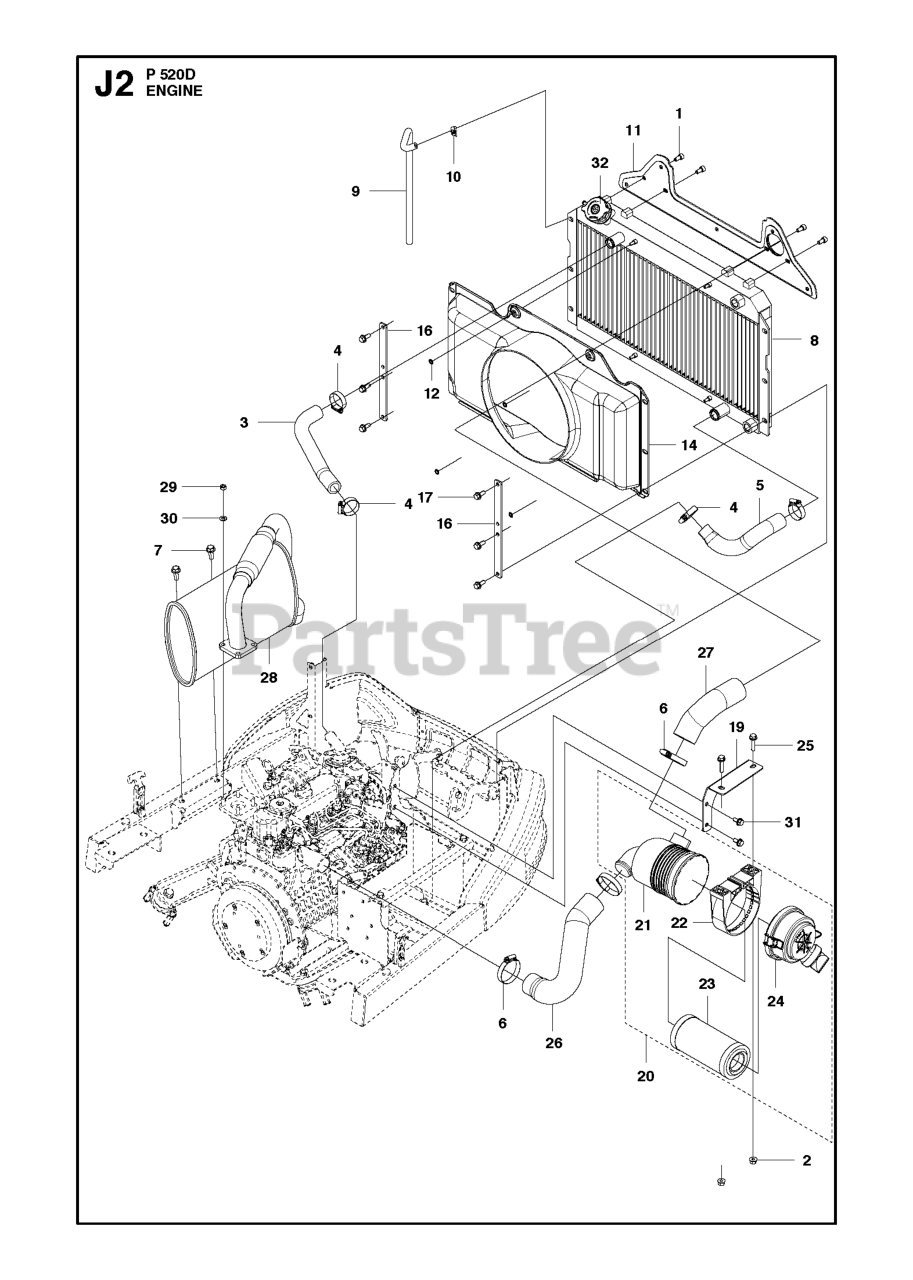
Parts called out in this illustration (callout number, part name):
2	NUT FLANGE
10	HOSE CLAMP FUEL
23	AIR FILTER
24	AIR FILTER END COVER
25	SCREW EHHFM
29	NUT
30	WASHER BRB 8.4X17
